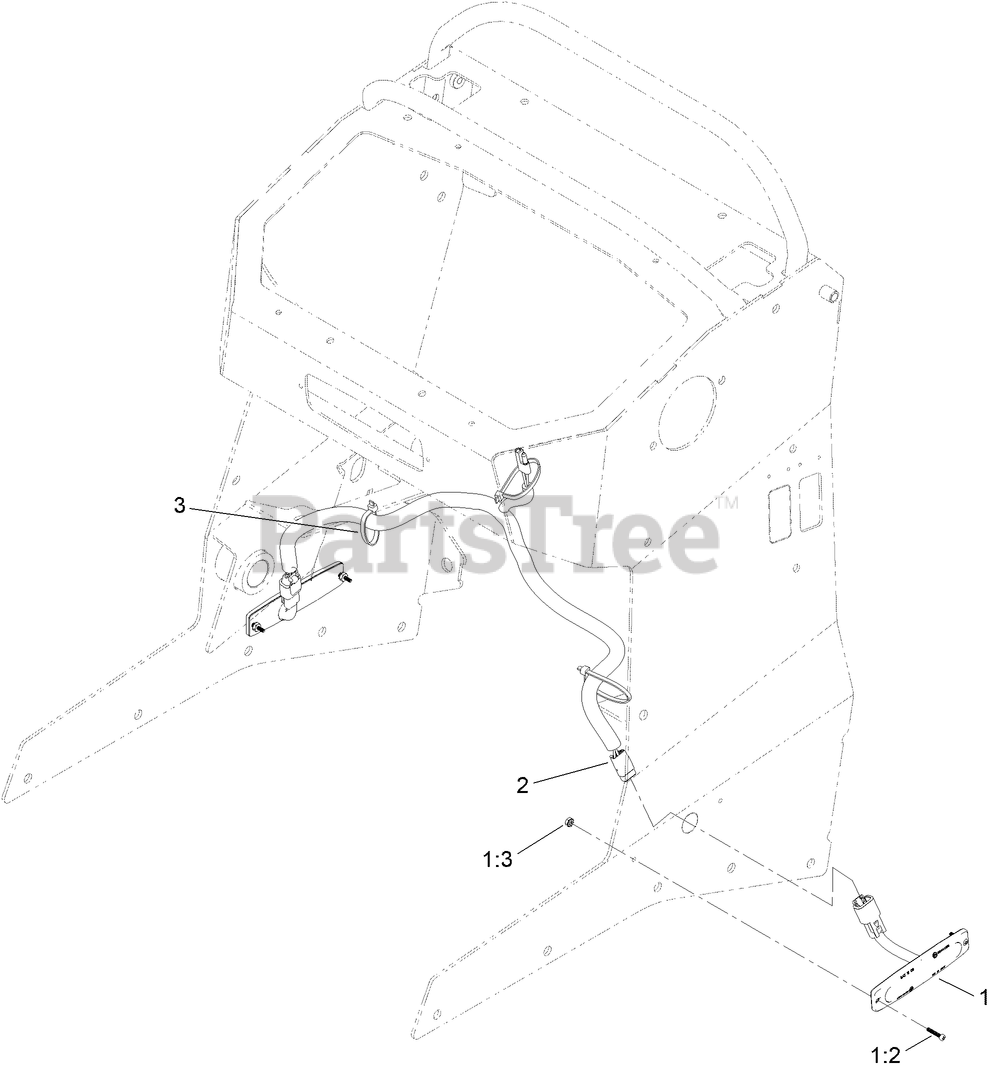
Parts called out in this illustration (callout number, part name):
1	LIGHT STROBE
1:2	SCR, MCH, 6-32 X 3/4, PHFH, STL, ROHS
1:3	NUT, HEX
2	HARNESS-WIRE, LED, STROBE
3	TIE-CABLE
